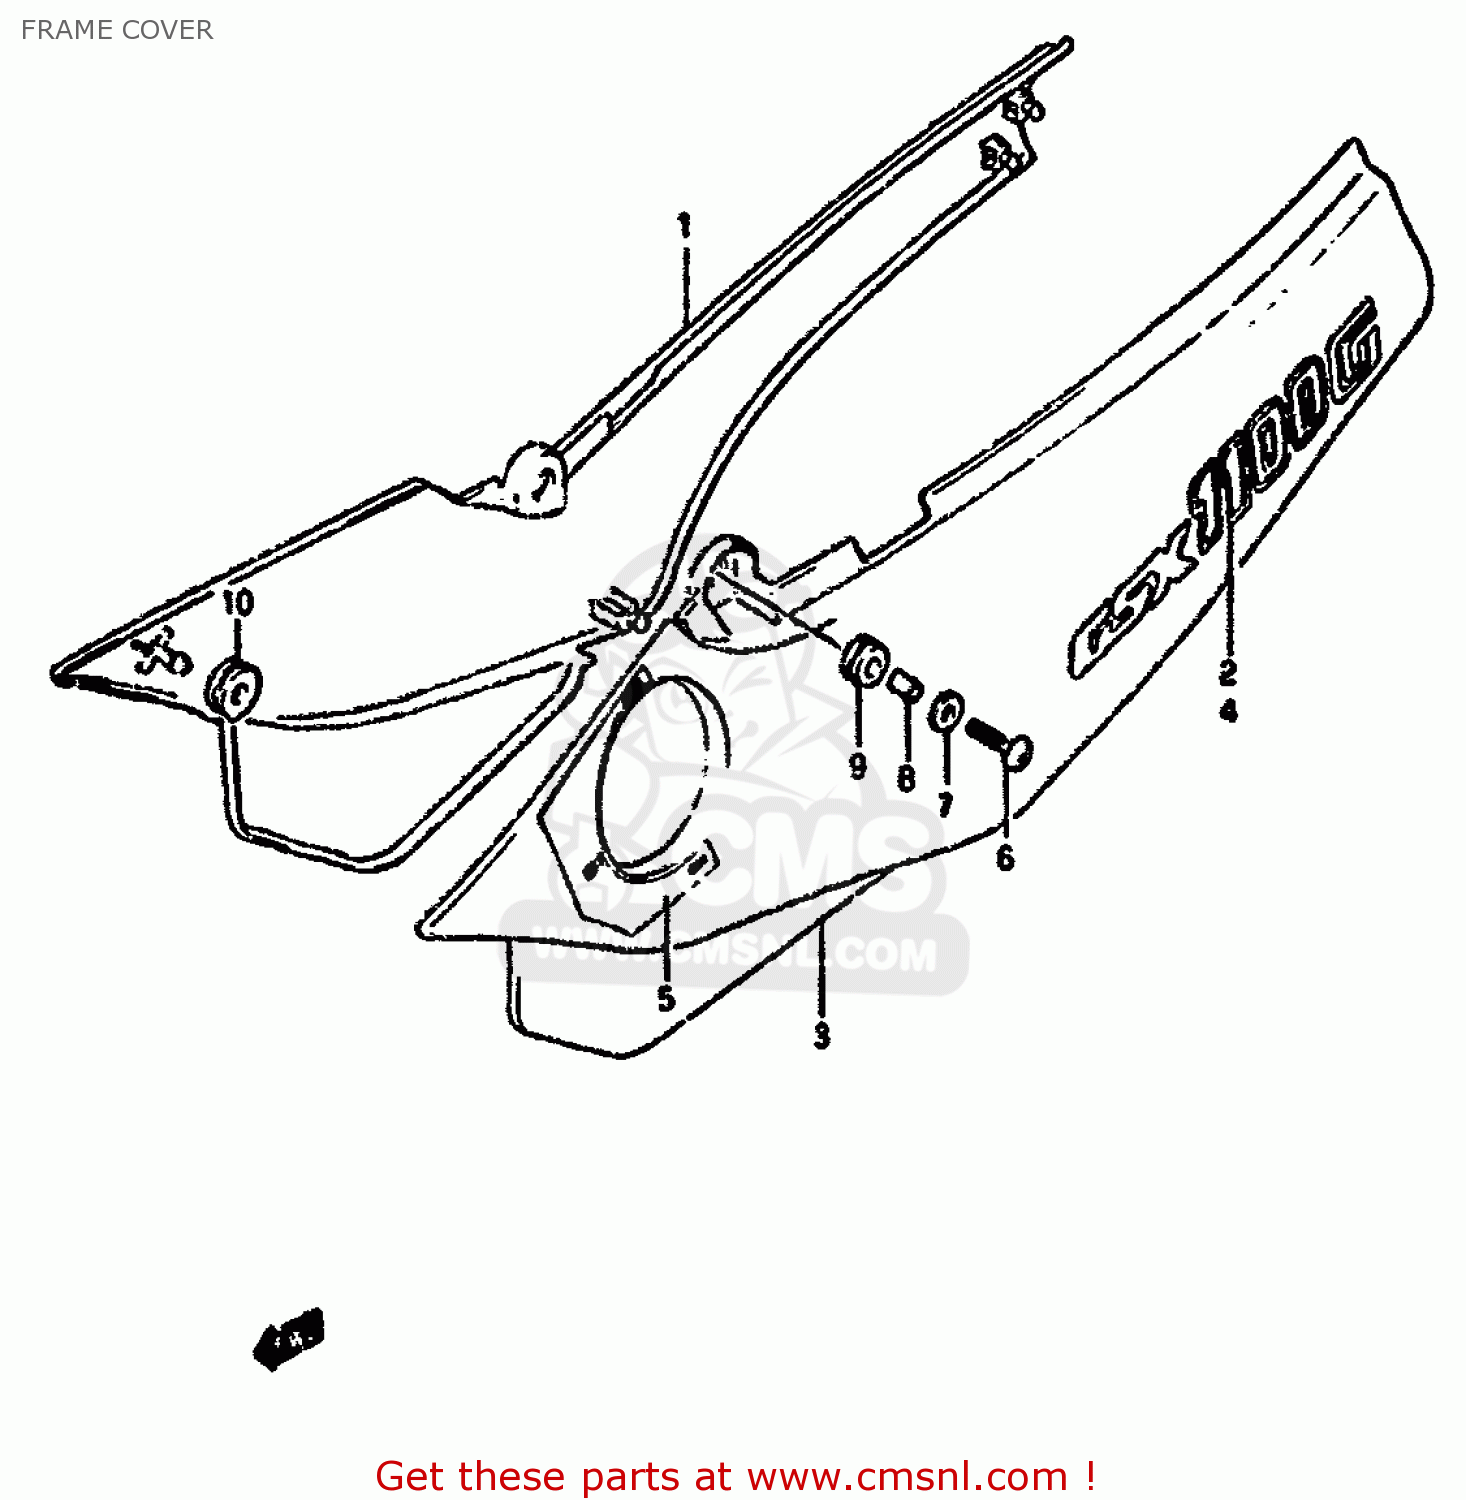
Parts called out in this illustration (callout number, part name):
1	COVER COMP,FRAME,RIGHT
2	EMBLEM,FRAME COVER
3	COVER COMP,FRAME,LEFT
4	EMBLEM,FRAME COVER
5	LABEL,FUEL COCK
6	SCREW
7	WASHER(6.5X18X1)
8	SPACER
9	CUSHION
10	CUSHION
